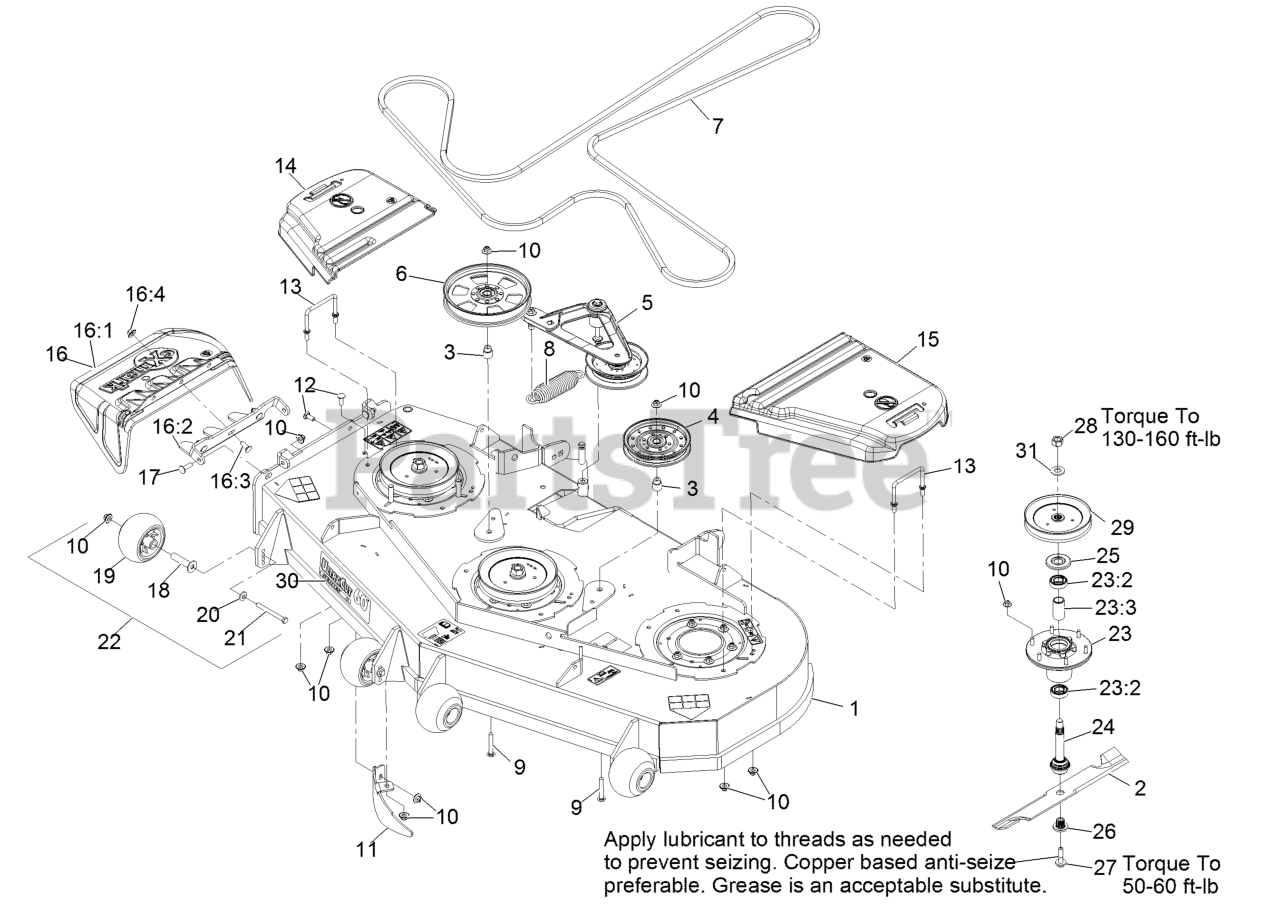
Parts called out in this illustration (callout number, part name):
1	DECK ASM,W/DECALS 60
2	Blade-Extreme 2, 20.50"
3	BUSHING-IDLER
5	DECK IDLER ASM
6	PULLEY-IDLER, FLAT
7	BELT,V-5V-198.75
8	SPRING-EXTENSION
9	SCREW-CARR
10	Nut-Nyloc 3/8-16 Flg
11	DOGLEG - LZ60
12	SCREW-CARR
13	WIREFORM-COVER
14	COVER-BELT, RH
15	COVER-BELT, LH
16	ASM,DISCHARGE CHUTE
16:1	CHUTE,DISCHARGE
16:2	BRACKET,DISCHARGE CHUTE
16:3	SCREW-CARR
16:4	Nut-Nyloc 3/8-16 Flg
17	Bolt-Carriage 3/8-16 X 1 1/4
18	AXLE, ROLLER
19	ROLLER-SCALP, ANTI
20	WASHER-BELLEVILLE
21	SCREW-HH 3/8-16 X 3 3/4 GR 8
22	KIT, ANTI-SCALP ROLLER
23	ASM-CUTTER HSG WITH BEARINGS
23:2	BEARING-BALL
23:3	SPACER-BEARING
24	ASM-SPINDLE AND SEAL
25	GUARD,BEARING TOP .989
26	BUSHING,SPLINED
27	SCREW,SEMS 1/2-20 X 2.19
28	NUT-HEX
29	SHEAVE,BLADE DRIVE 7.25
30	DECAL,ULTRACUT 60 SERIES
